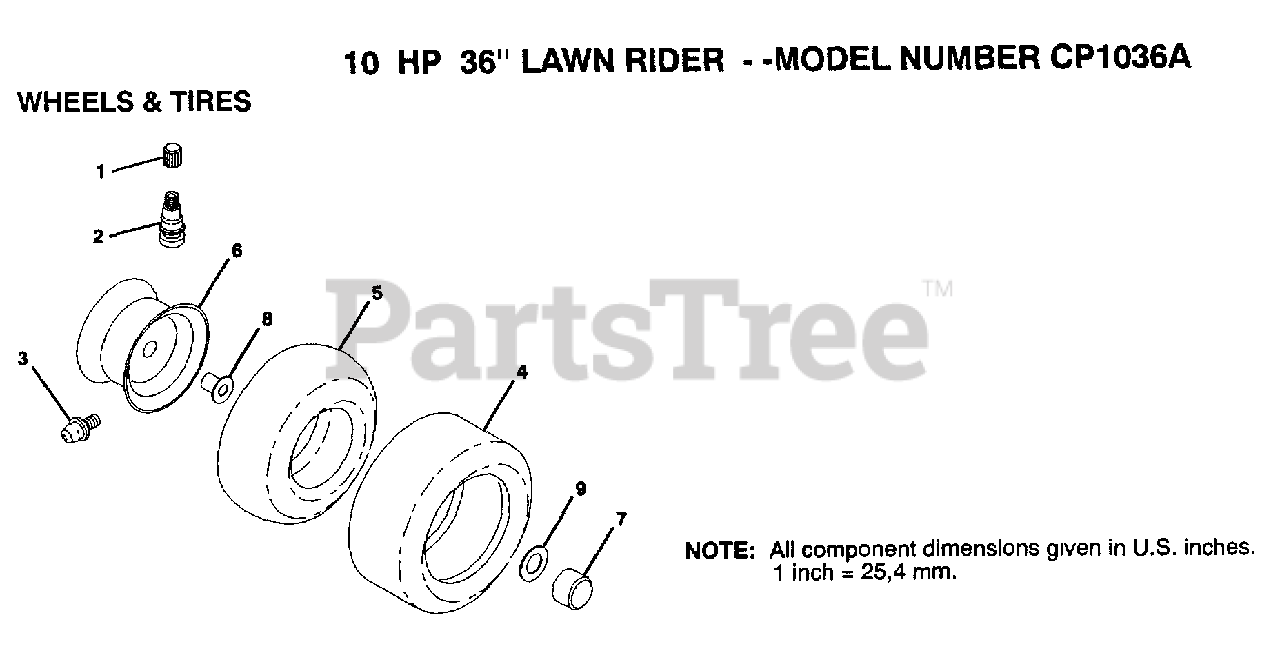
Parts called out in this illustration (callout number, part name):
1	VALVE CAP
2	VALVE STEM LT
3	FITTING LT
5	TUBE.5.3/4.5/6
7	HUB CAP
8	"FLANGE, BEARING"
9	WASHER
